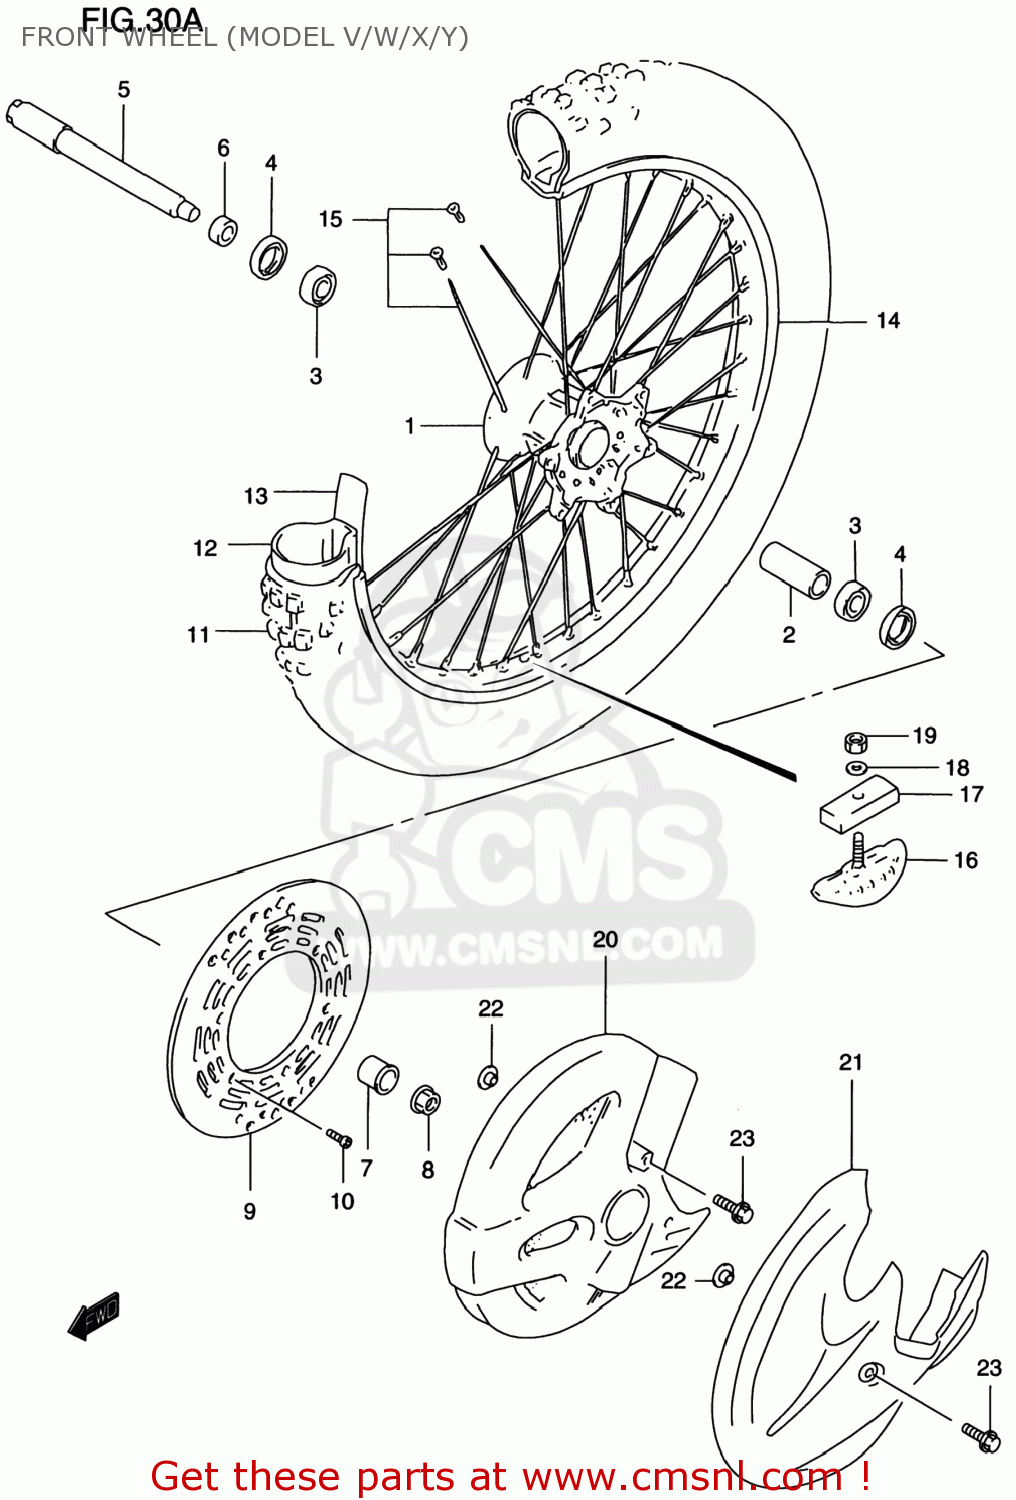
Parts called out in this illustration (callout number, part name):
1	HUB,FR
2	SPACER,FR HUB BEARING
3	BEARING
4	SEAL,OIL(25X37X6)
5	AXLE,FRONT
6	SPACER,FR AXLE,R
7	SPACER,FR AXLE,L
8	NUT
9	DISC,FR BRAKE
10	SCREW
11	TIRE, FRONT
12	TUBE
13	PROTECTOR,WHEEL INNER
14	RIM,FR WHEEL(1.60X21 AL)(.WHT)
15	SPOKE SET,FR WHEEL
16	STOPPER,BEAD
17	CUSHION,BEAD STOPPER
18	WASHER
19	NUT
20	COVER,FRONT BRAKE DISC
21	COVER,FR BRAKE DISC
22	WASHER
23	BOLT(6X16)
